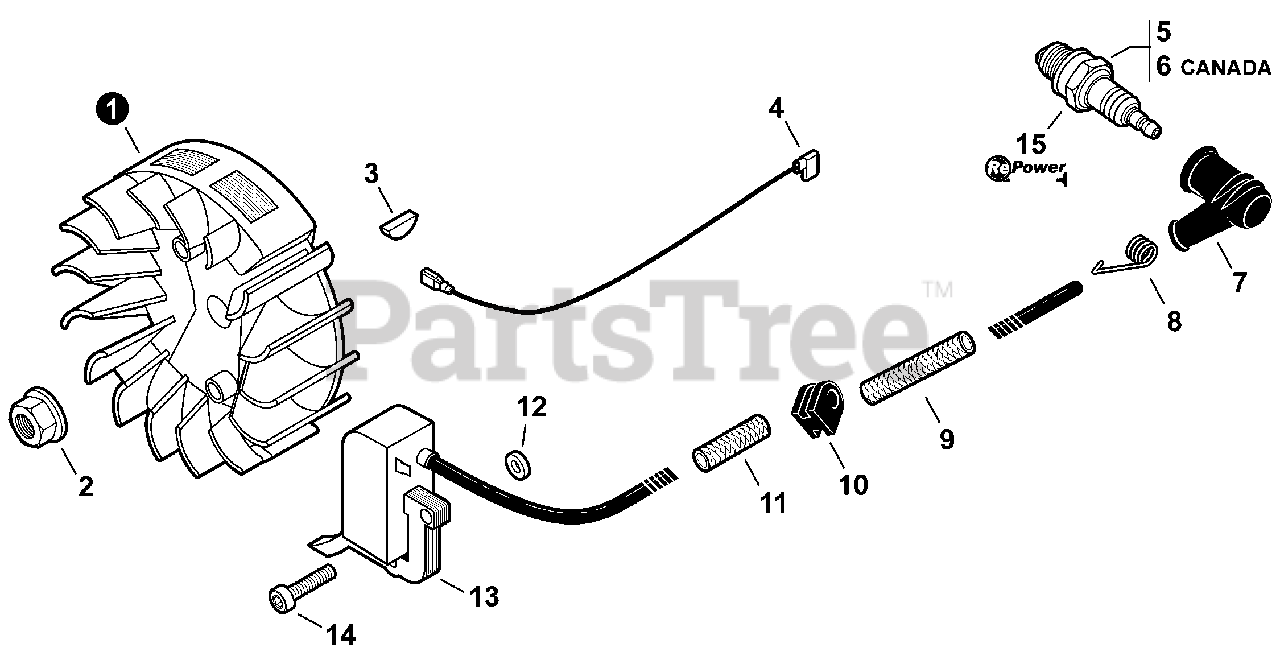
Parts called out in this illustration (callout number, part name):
1	FLYWHEEL
2	NUT, FLANGE M8
3	KEY, WOODRUFF
4	LEAD - IGNITION
5	SPARK PLUG - BPM8Y
6	SPARK PLUG - BPMR8Y
7	CAP, SPARK PLUG
8	TERMINAL, SPARK PLUG
9	TUBE, INSULATOR HST-10 7×0.8×40
10	GROMMET, HT CORD
11	TUBE, INSULATOR 7×8.6×30
12	WASHER 5.2×12×3
13	COIL, IGNITION
14	BOLT, TORX 5×20
15	TUNE-UP KIT - REPOWER
